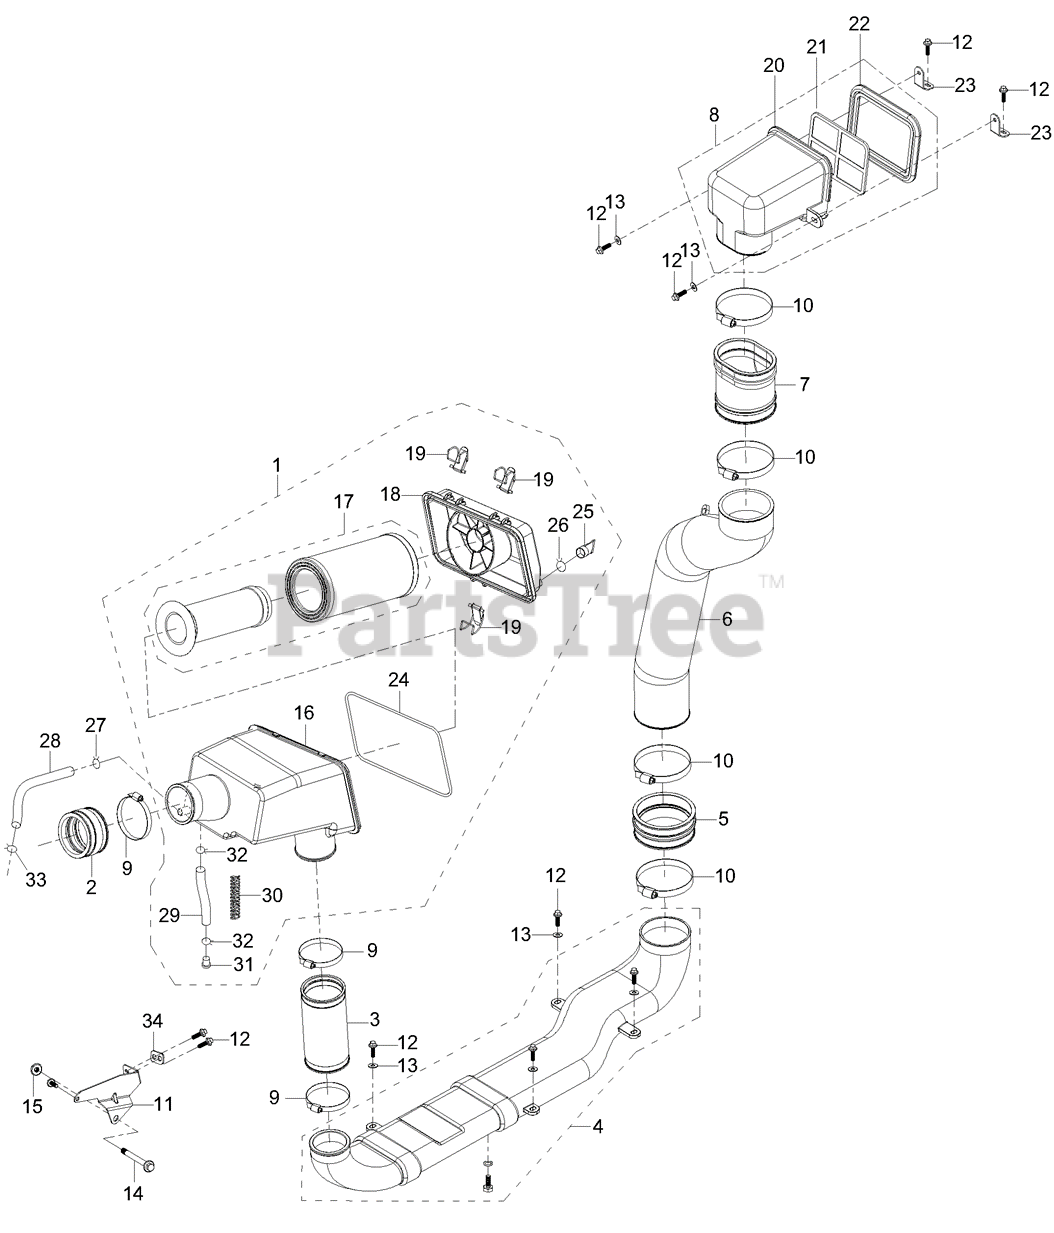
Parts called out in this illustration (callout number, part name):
1	AIR CLEANER 2ND ASSEMBLY
2	INNER THROTTLE SLEEVE
3	AIR CLEANER SLEEVE - INNER
4	AIR CLEANER DUCT - INNER
5	CLUTCH AIR INLET SLEEVE
6	AIR CLEANER DUCT - INNER
7	AIR CLEANER SLEEVE - INNER
8	AIR CLEANER 1ST ASSEMBLY
9	SCREW HOOP
10	NARROW BAND CLAMP
11	AIR CLEANER STRAP
12	HEXAGON FLANGE BOLT M6X16
13	FLAT WASHER
14	HEX FLANGE BOLT M10X1.25X55
15	LOCK NUT M10X1.25
16	SECONDARY AIR BOX
17	SECONDARY AIR FILTER
18	AIRBOX COVER
20	PRIMARY FILTER BODY
21	PRIMARY AIR FILTER
22	PRIMARY AIR FILTER COVER
24	SECONDARY FILTER SEAL
27	SPRING CLAMP
30	COMPRESSION SPRING
31	DRAIN VALVE
32	O-RING 140X2.65
33	SPRING CLAMP
34	AIR FILTER MOUNTING WASHER
